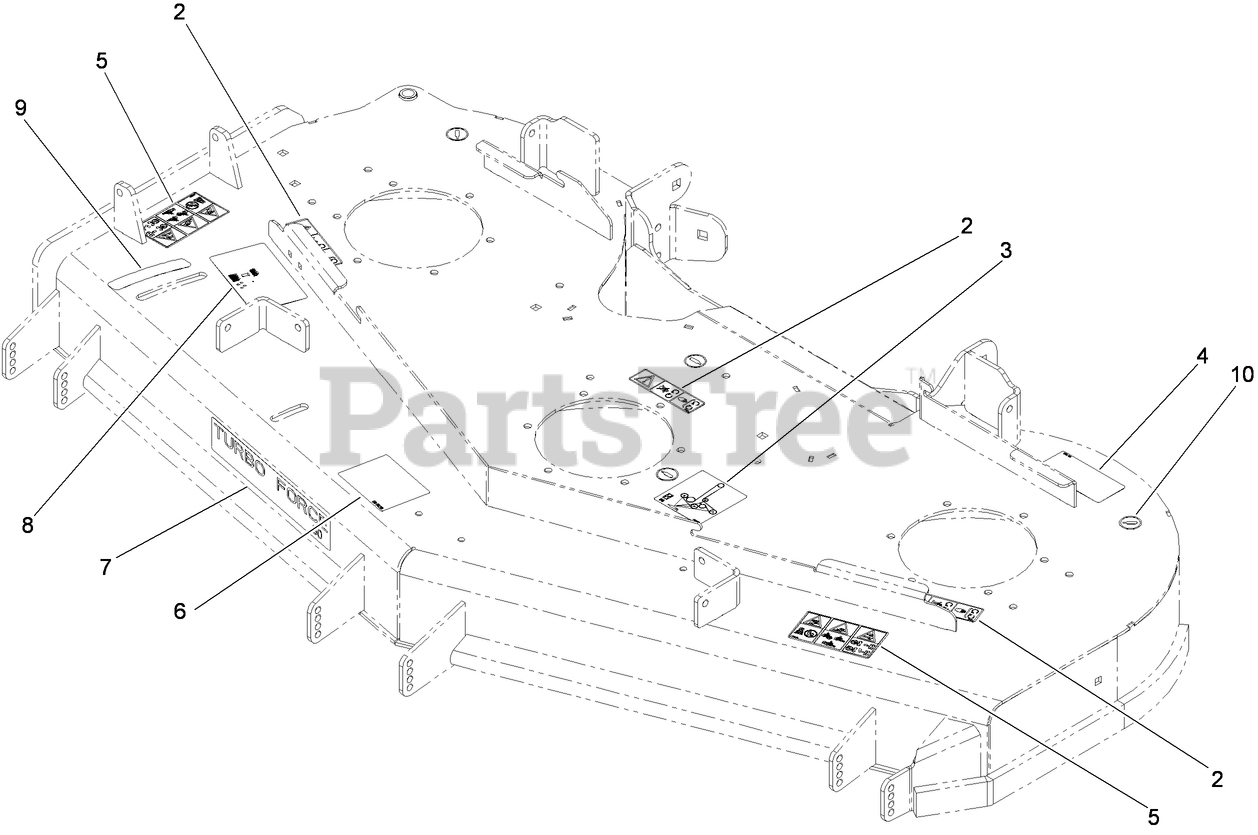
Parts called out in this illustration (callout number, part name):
2	DECAL-MISSING, COVER
3	DECAL-ROUTING, DECK BELT
4	DECAL-TORQUE, BLADE BOLT
5	DECAL-DANGER
6	DECAL-ANTI SCALP
8	DECAL-ADJUSTMENT, BAFFLE
9	DECAL-SETTING, BAFFLE
10	DECAL-GREASE
